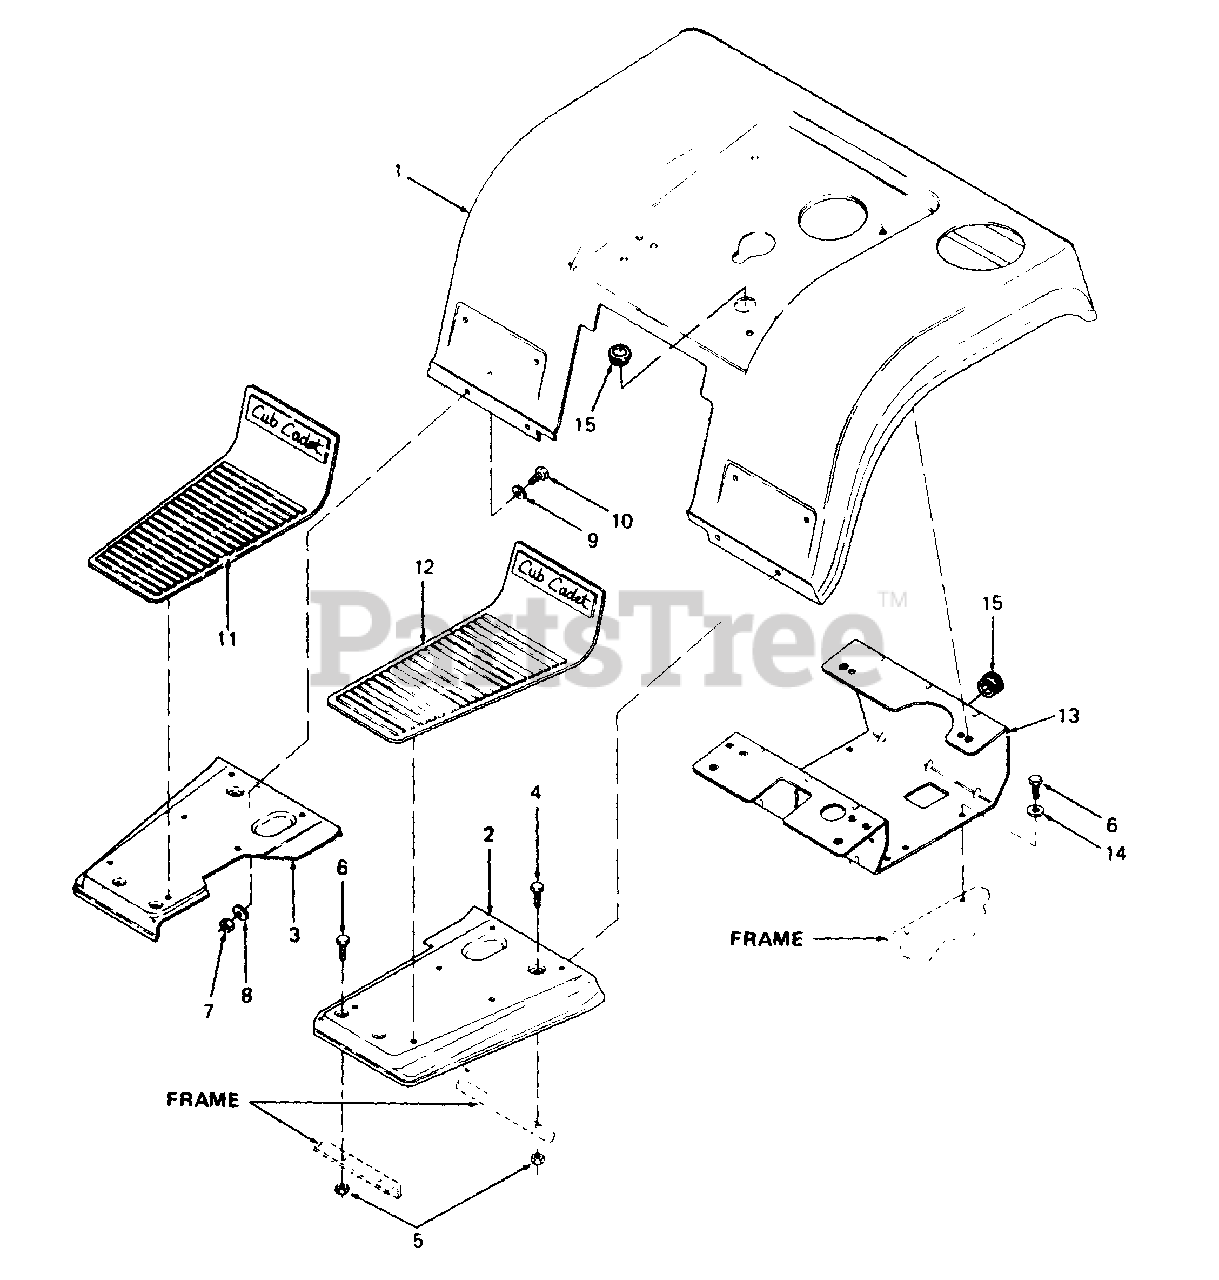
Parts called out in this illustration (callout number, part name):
5	Nut, Hex Center Lock, 5/16-18 GR5
6	Screw, Hex Cap, 5/16-18 x .62 Lg GR5
7	Nut, Hex Patch Lock, 1/4-20
8	Washer, Bell, .265 x .75 x .062 Thk
9	Washer, Flat, .281 x .73 x .063 Thk
10	Screw, Hex, Cap, 1/4-20 x .50 Lg GR5
11	Foot Pad - RH
12	Foot Pad - LH
14	Washer, Flat, .34 x .68 x .062 Thk
15	Bushing, Snap
